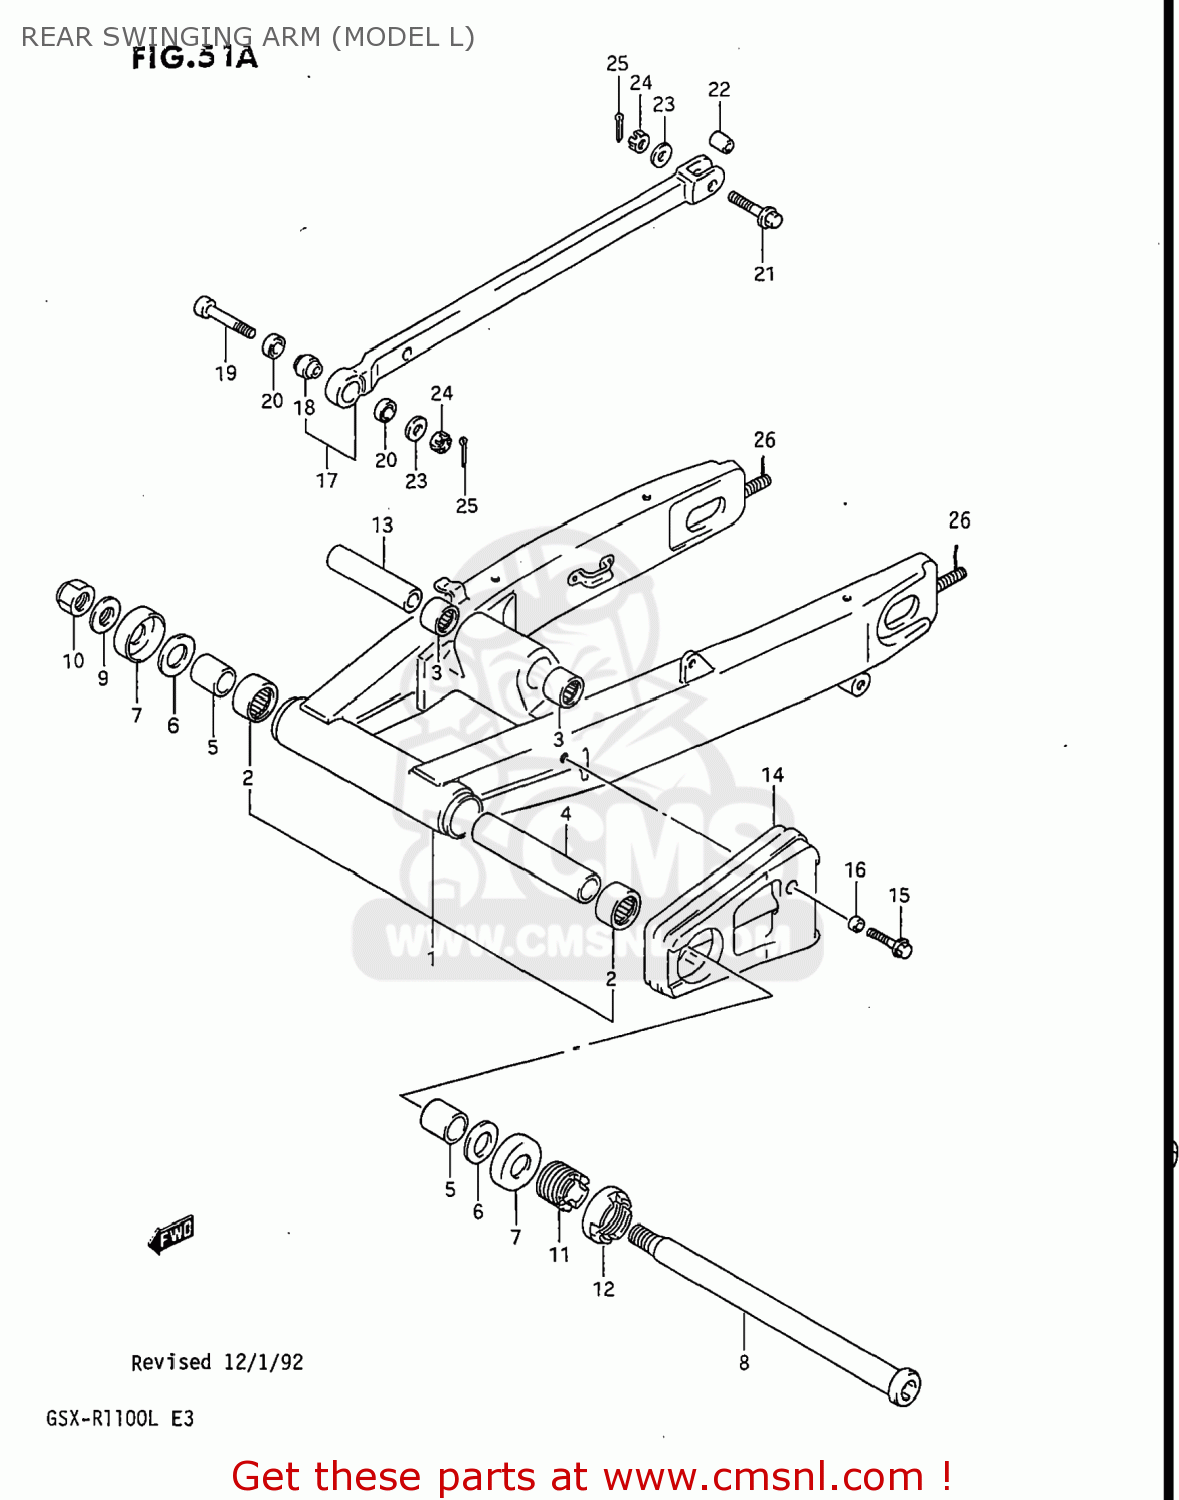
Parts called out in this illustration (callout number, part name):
1	SWING ARM ASSEMBLY,REAR
2	BEARING(25X33X30)
3	BEARING(20X27X23.5)
4	SPACER,RR SWGARM PIVOT CTR
5	SPACER,RR SWGARM PIVOT BERRING
6	WASHER
7	DUST SEAL,RR SWGARM PIVOT
8	SHAFT,REAR SWING ARM PIVOT
9	WASHER
10	NUT
11	BOLT,RR SWGARM PIVOT
12	NUT,REAR SWING ARM PIVOT
13	SPACER,RR CUSHION ROD
14	BUFFER,CHAIN TOUCH DEFENSE
15	BOLT 6X20,WITH PLAIN WASHER
16	SPACER
17	TORQUE LINK SET,REAR
18	SPHERICAL BEARING,TORQUE
19	BOLT(8X48)
20	21
21	BOLT(8X38)
22	SPACER,RR TORQUE LINK RR
23	WASHER
24	NUT 8MM
25	PIN 20X20
